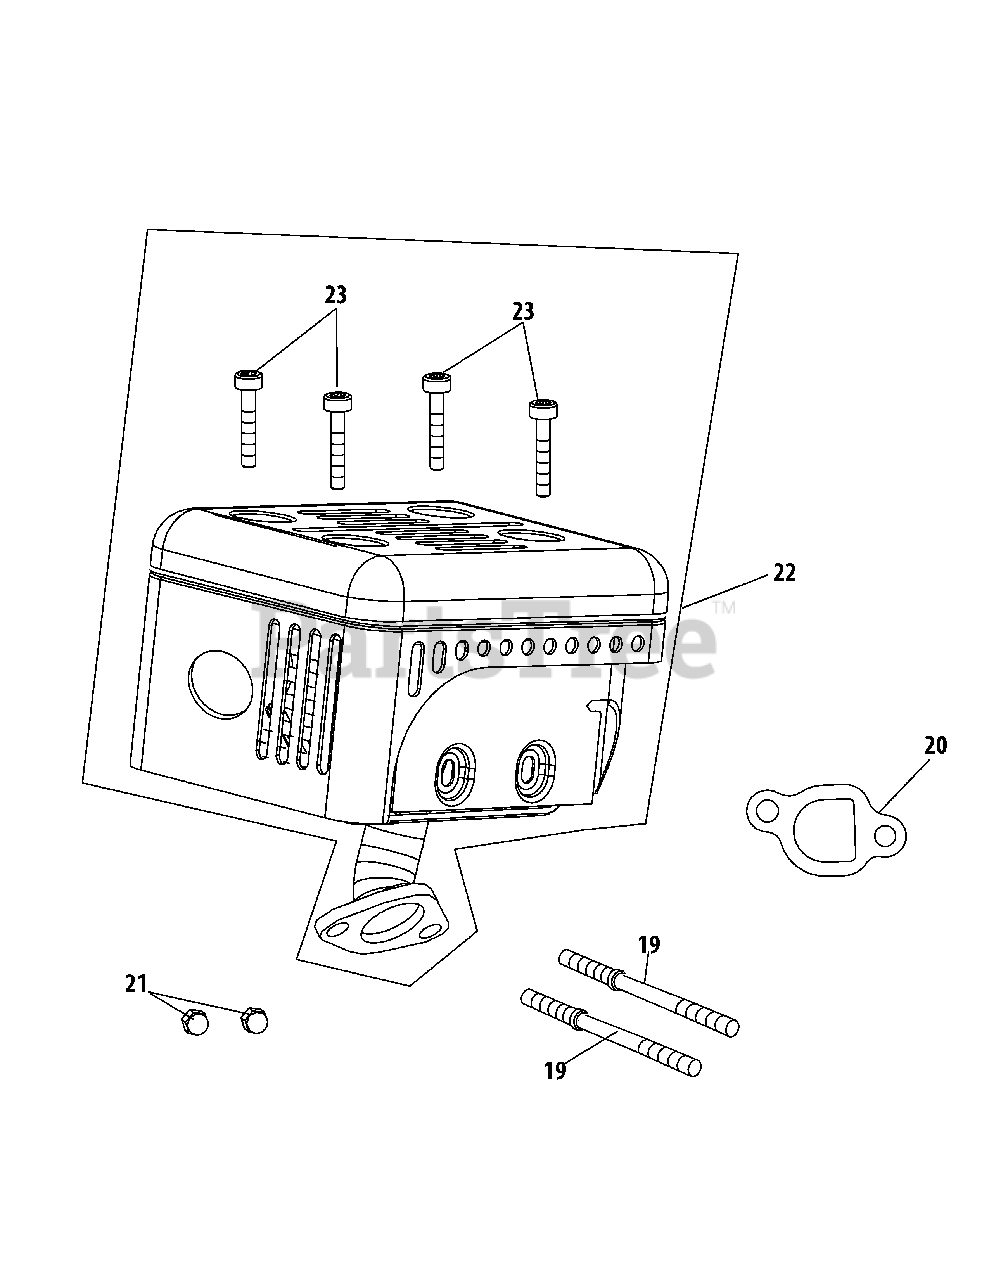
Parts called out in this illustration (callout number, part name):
19	Muffler Stud
19	Muffler Stud Assembly
20	Muffler Gasket
21	Nut, M8
22	Muffler Assembly
23	Bolt M5×10
